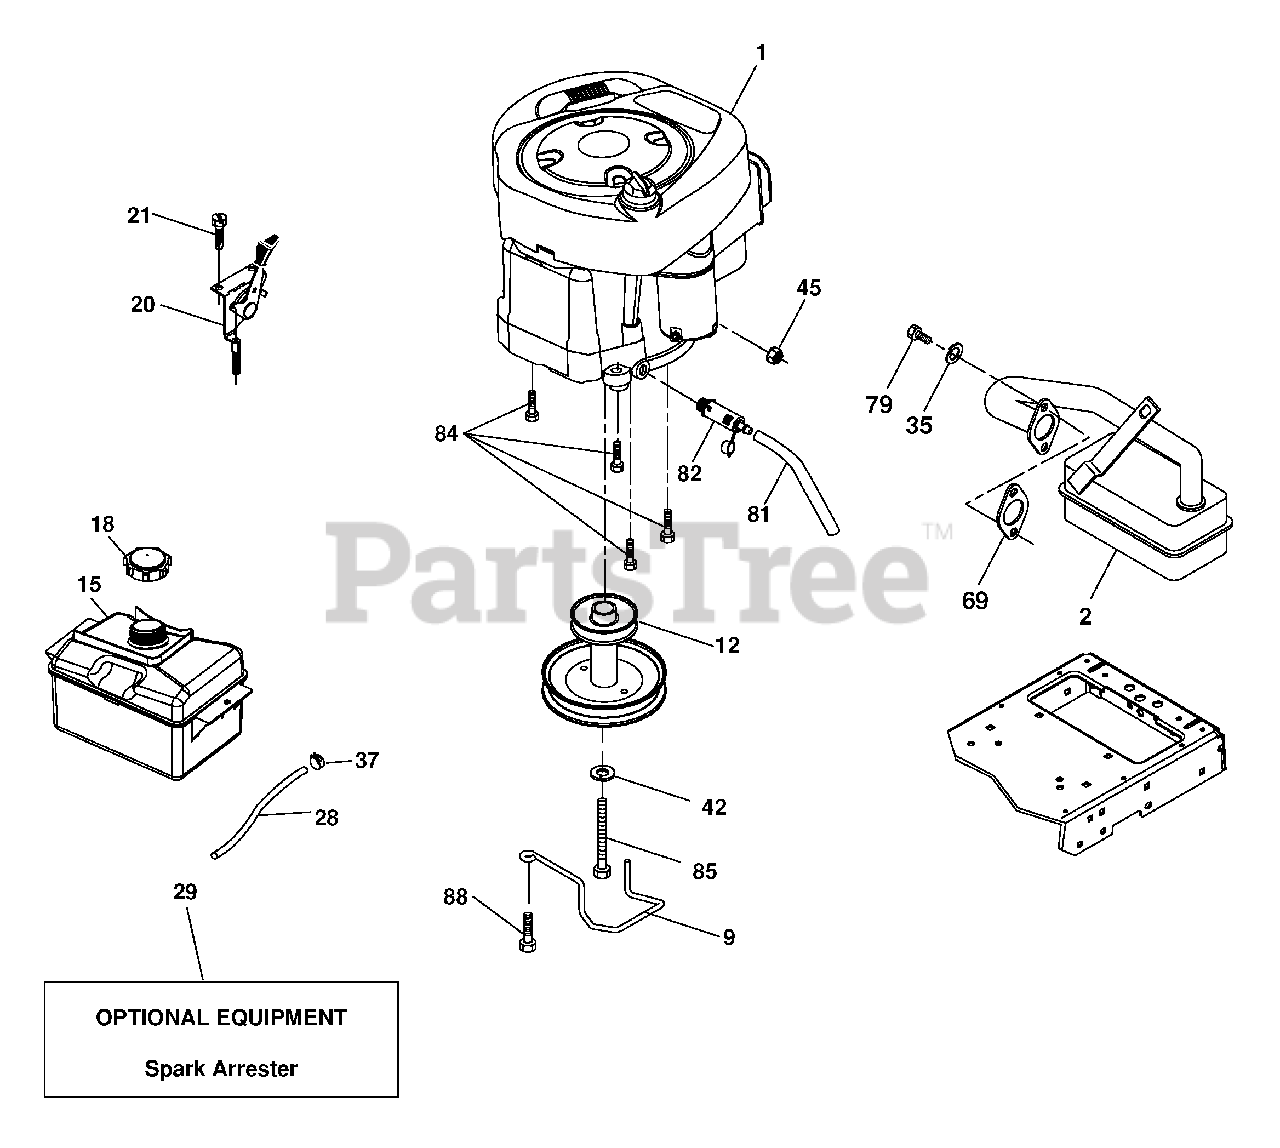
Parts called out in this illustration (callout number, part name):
2	Muffler
9	Keeper Belt Engine
12	Pulley Engine
15	Tank Fuel
18	Cap Asm
20	Control Throttle/Choke
21	Screw 10 x 3/4 Single Lead-Hex
28	Fuel Line
29	Spark Arrester Kit
35	Washer Split
37	Clamp Hose
42	Washer Lock 7/16
45	Nut Keps Hex 1/4-20 unc
69	Gasket
79	Screw Socket Head 5/16-18 x .75
81	Tube Drain Oil Easy
82	Plug Drain Oil
84	Screw 3/8-16 x 1-1/4
85	Bolt Hex 7/16-20 x 4 x Gr. 5-1.5
88	Screw 3/8-16 x 1
